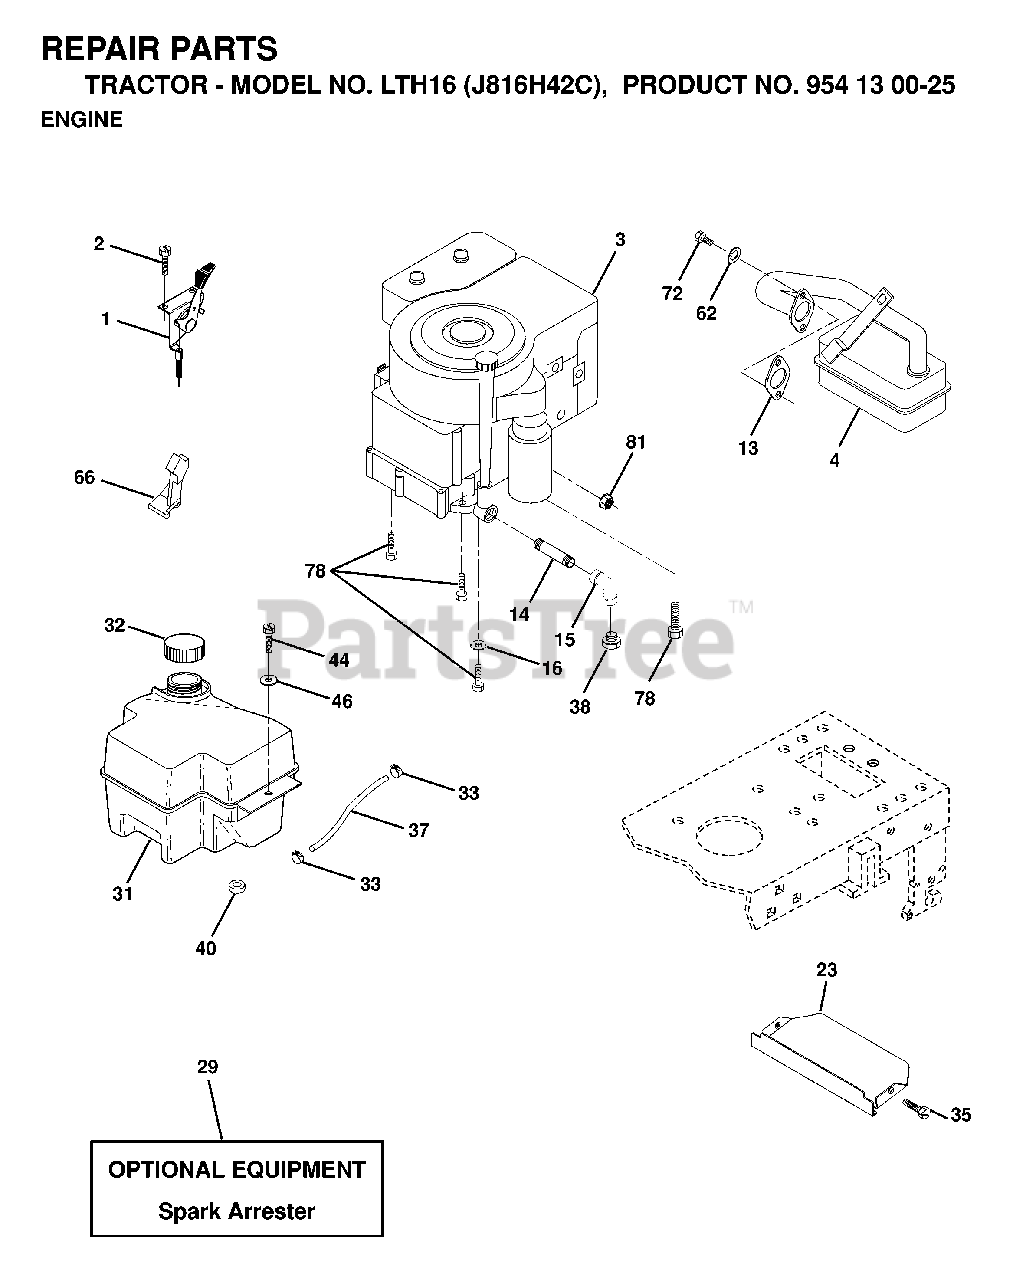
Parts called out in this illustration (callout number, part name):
1	CONTROL
2	SCREW LT
13	GASKET ENG
15	ELBOW
16	LOCKWASHER
23	PROTECTOR
29	ARRESTER SPARK (OPTIONAL)
31	FUEL TANK
32	FUEL CAP
33	HOSE CLAMP
35	SCREW
37	LINE.FUEL.20
40	GROMMET T
44	SCREW HEX CRT
62	LOCKWASHER
66	STOP THROTTLE
72	SCREW
78	SCREW
81	NUT FLANGE 1/4-20 STARTER NUT
